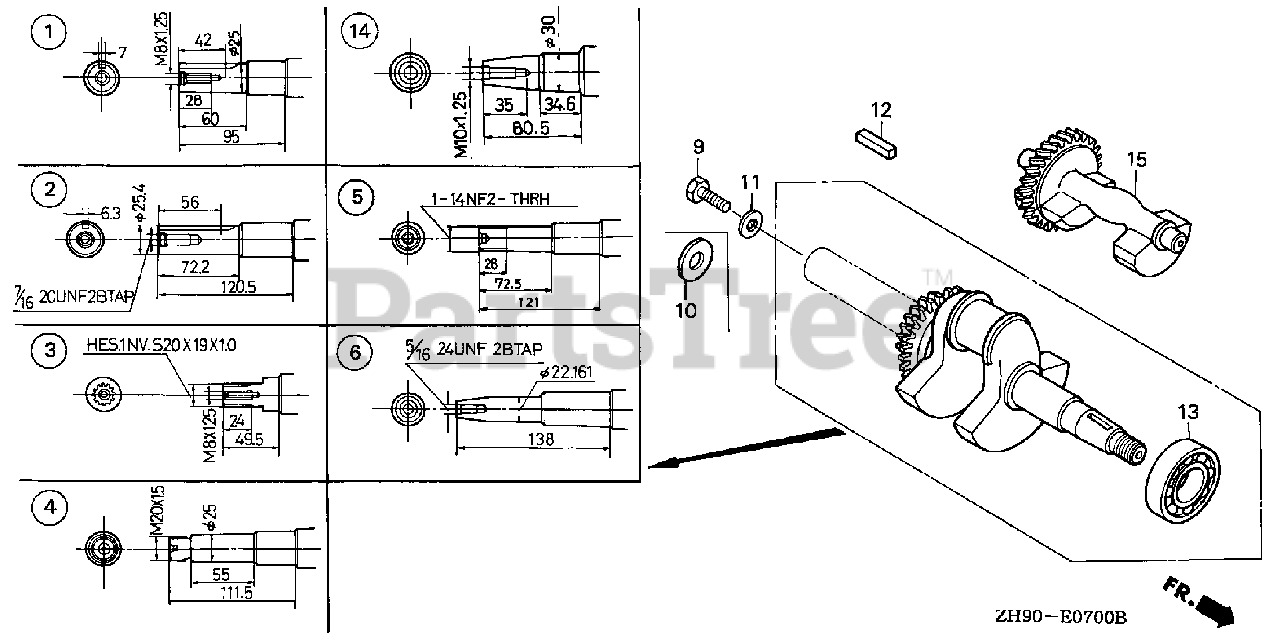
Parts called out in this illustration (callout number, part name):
2	CRANKSHAFT (Q-TYPE)(BALANCER)
12	KEY (6.3X6.3X43)
13	BEARING, RADIAL BALL (6206 SH)
15	WEIGHT, BALANCER
